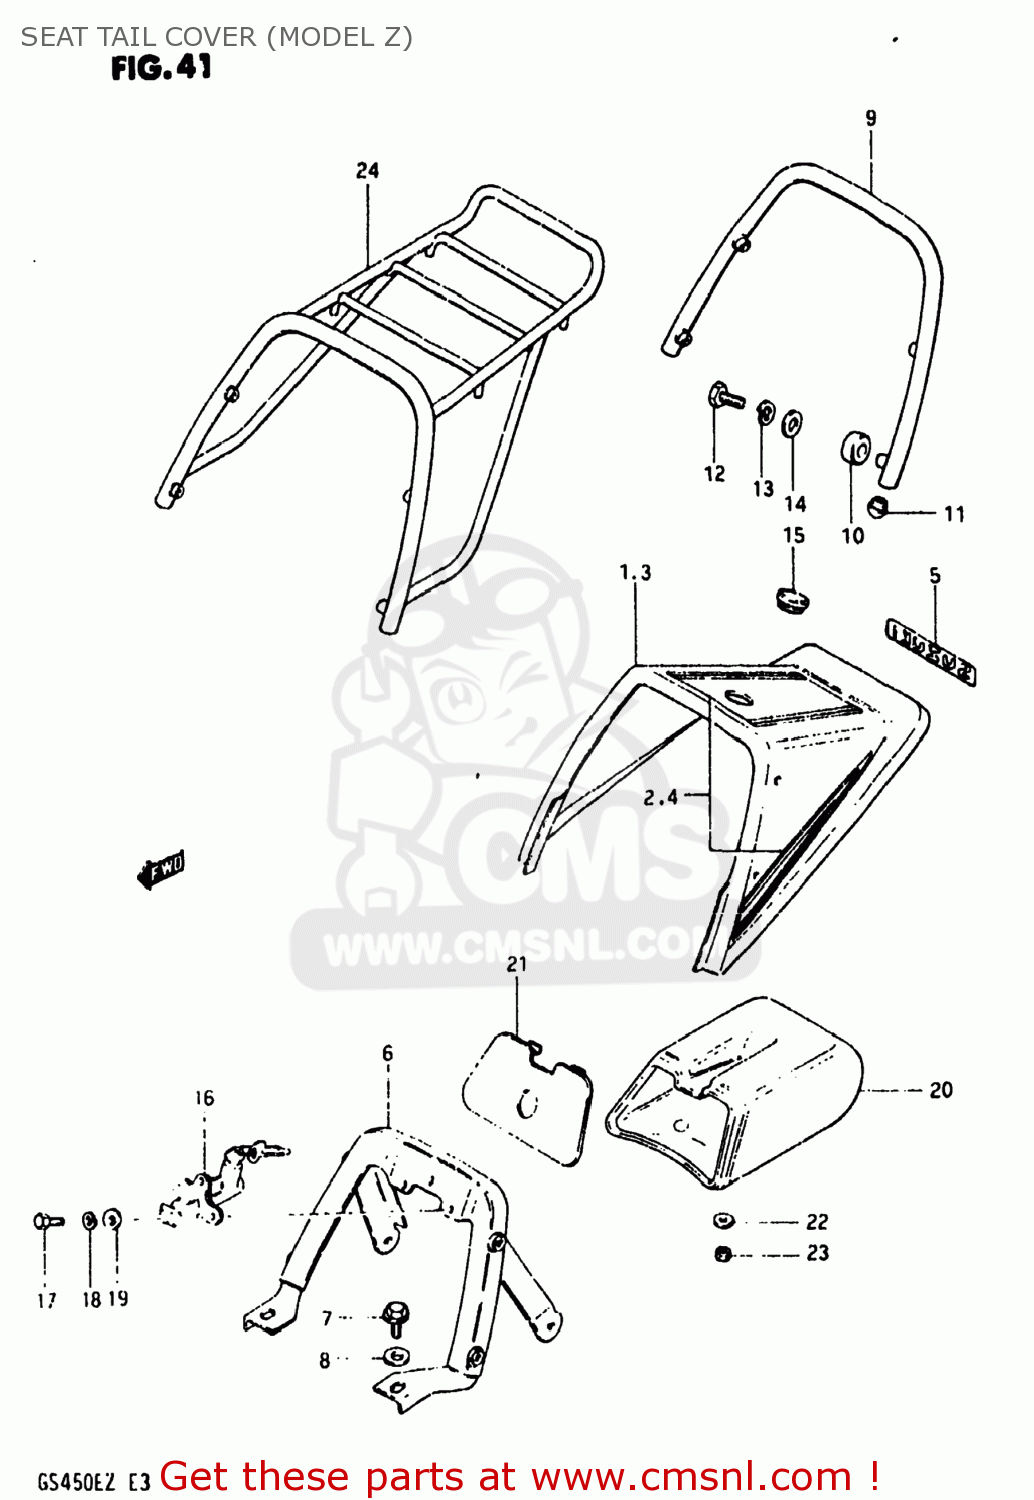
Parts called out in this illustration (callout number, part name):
1	COVER,SEAT TAIL
2	TAPE SET,SEAT TAIL COVER
3	COVER,SEAT TAIL
4	TAPE SET,SEAT TAIL COVER
5	EMBLEM (GOLD/BLACK)
6	BRACKET, SEAT TAIL COVER
7	BOLT
8	WASHER (8.7X22X2)
9	HANDLE,PILLION RIDER
10	CUSHION
11	END,SHEET HANDLE
12	BOLT (8X30)
13	LOCK WASHER
14	WASHER
15	GROMMET,SEAT LOCK HOLE
16	LOCK SET,SEAT
17	BOLT
18	LOCK WASHER
19	WASHER
20	BOX, SEAT TAIL
21	LID,SEAT TAIL BOX
22	WASHER
23	NUT 6MM
24	CARRIER
